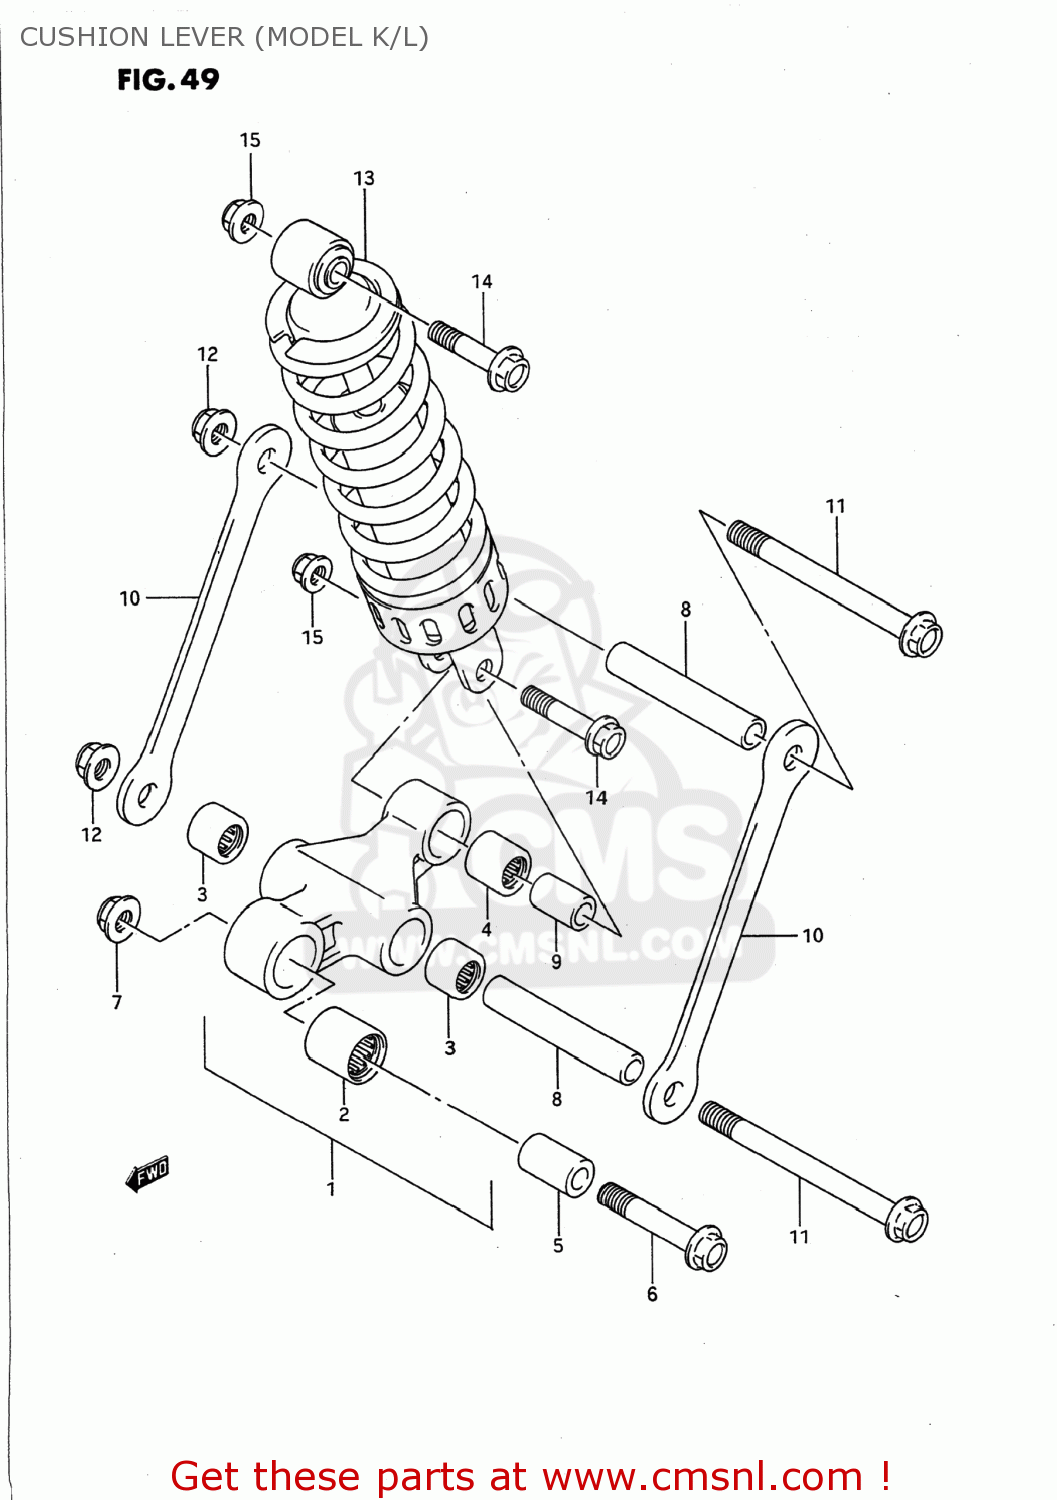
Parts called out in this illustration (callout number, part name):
1	LEVER SET,RR CUSHION
2	BEARING(20X27X26)
3	BEARING(17X24X25)
4	BEARING(17X24X26)
5	SPACER,REAR CUSHION LEVER
6	BOLT(12X57)
7	NUT 12MM
8	SPACER(12X17X89)
9	SPACER,RR CUSHION LEVER
10	ROD,REAR CUSHION LEVER
11	BOLT(12X118)
12	NUT 12MM
13	ABSORBER ASSEMBLY,REAR SHOCK
14	BOLT(10X52)
15	NUT
